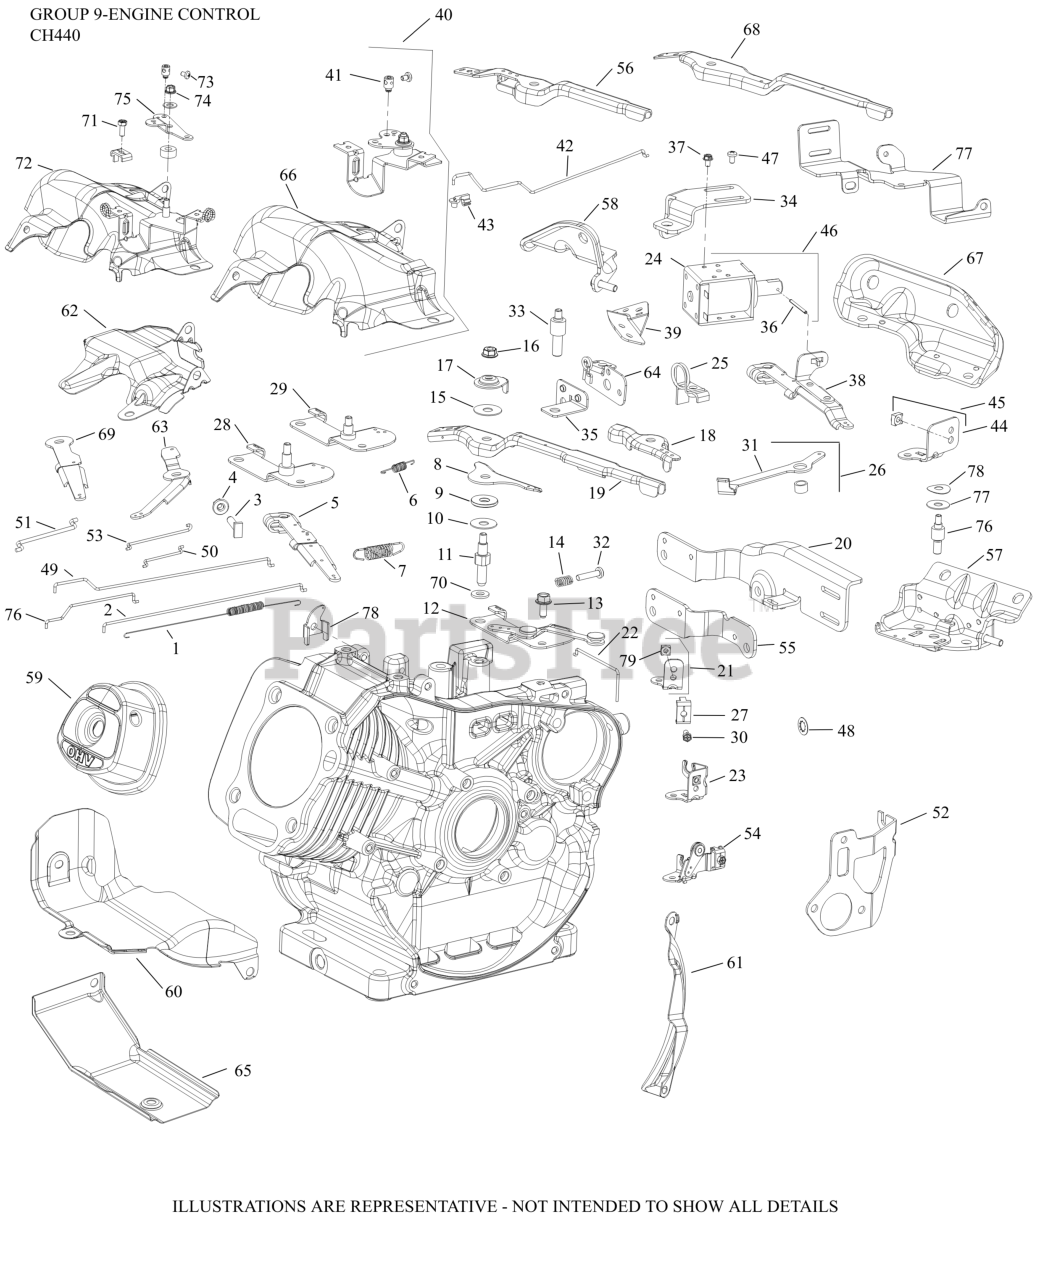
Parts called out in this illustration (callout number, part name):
1	SPRING, LINKAGE
2	LINKAGE, GOVERNOR
3	SCREW, RECTANGLE HEAD (M6)
4	NUT, HEX FLANGE (M6) - USE 14 100 16-S
5	KIT, GOVERNOR LEVER
7	SPRING, GOVERNOR
8	LEVER, FIXED SPEED
13	SCREW, HEX FLANGE (M6)-USE 25 086 433-S
14	SPRING, COMPRESSION
16	NUT, HEX FLANGE LOCK (M6)
23	BRCKT ASSY,REMOTE CHOKE-USE 17 126 289-S
27	CLAMP, CABLE
30	SCREW, HEX/PHILLIPS M5
32	SCREW, SPEED ADJUSTING
33	STUD, CONTROL LEVER
35	BRACKET, CONTROL
